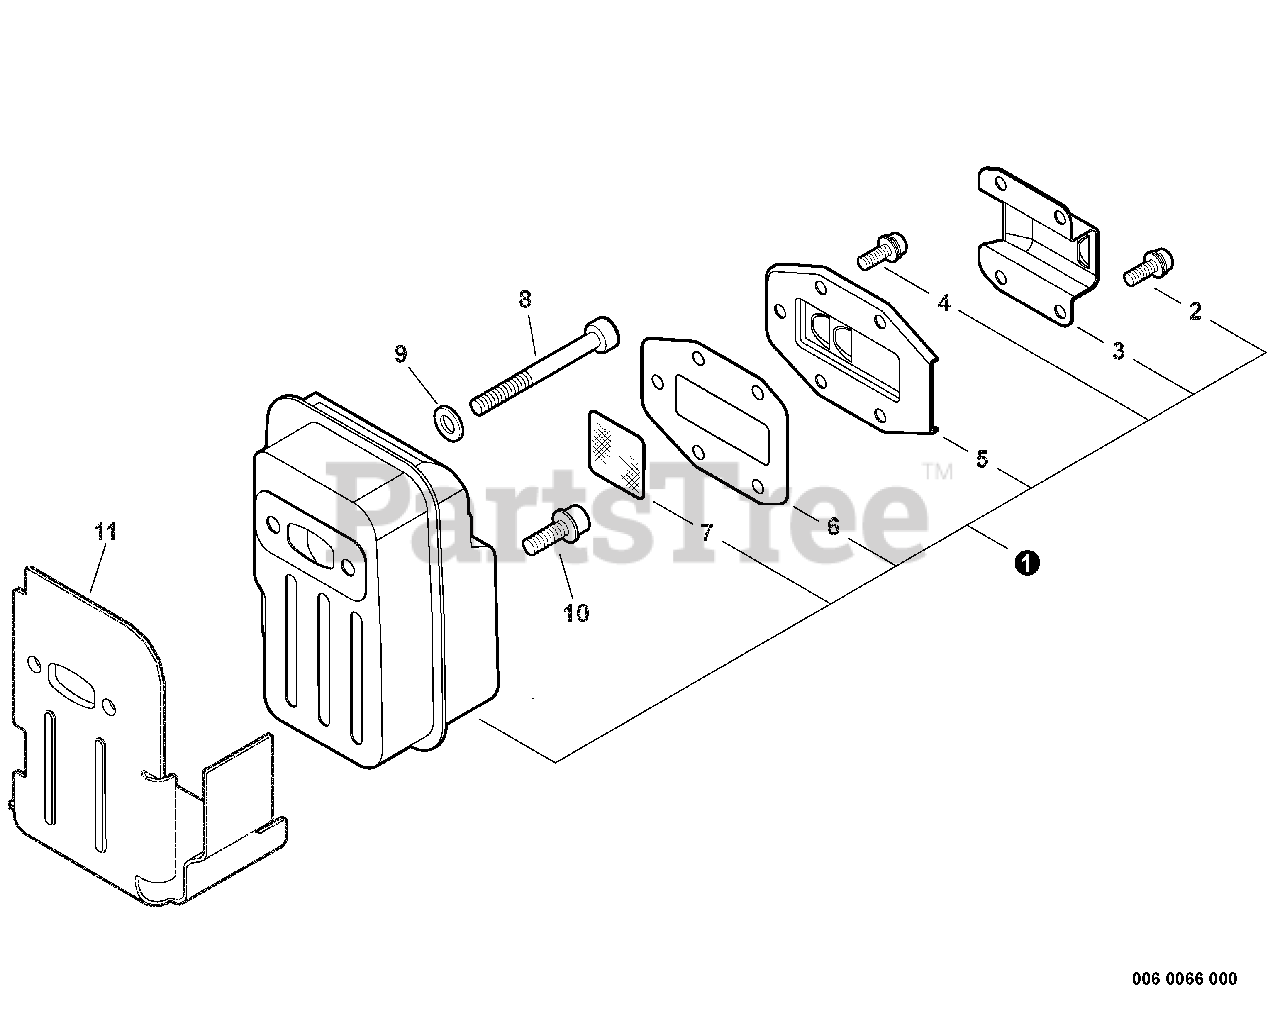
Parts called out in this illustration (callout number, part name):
1	MUFFLER ASSY
2	SCREW - 4X8
3	GUIDE, EXHAUST - OUTER
4	SCREW - 4X8
5	GUIDE, EXHAUST - INNER
6	GASKET, EXHAUST
7	SCREEN, SPARK ARRESTOR
8	SCREW - 5X55
9	WASHER - 5
10	SCREW - 5X12
11	SHIELD, EXHAUST
